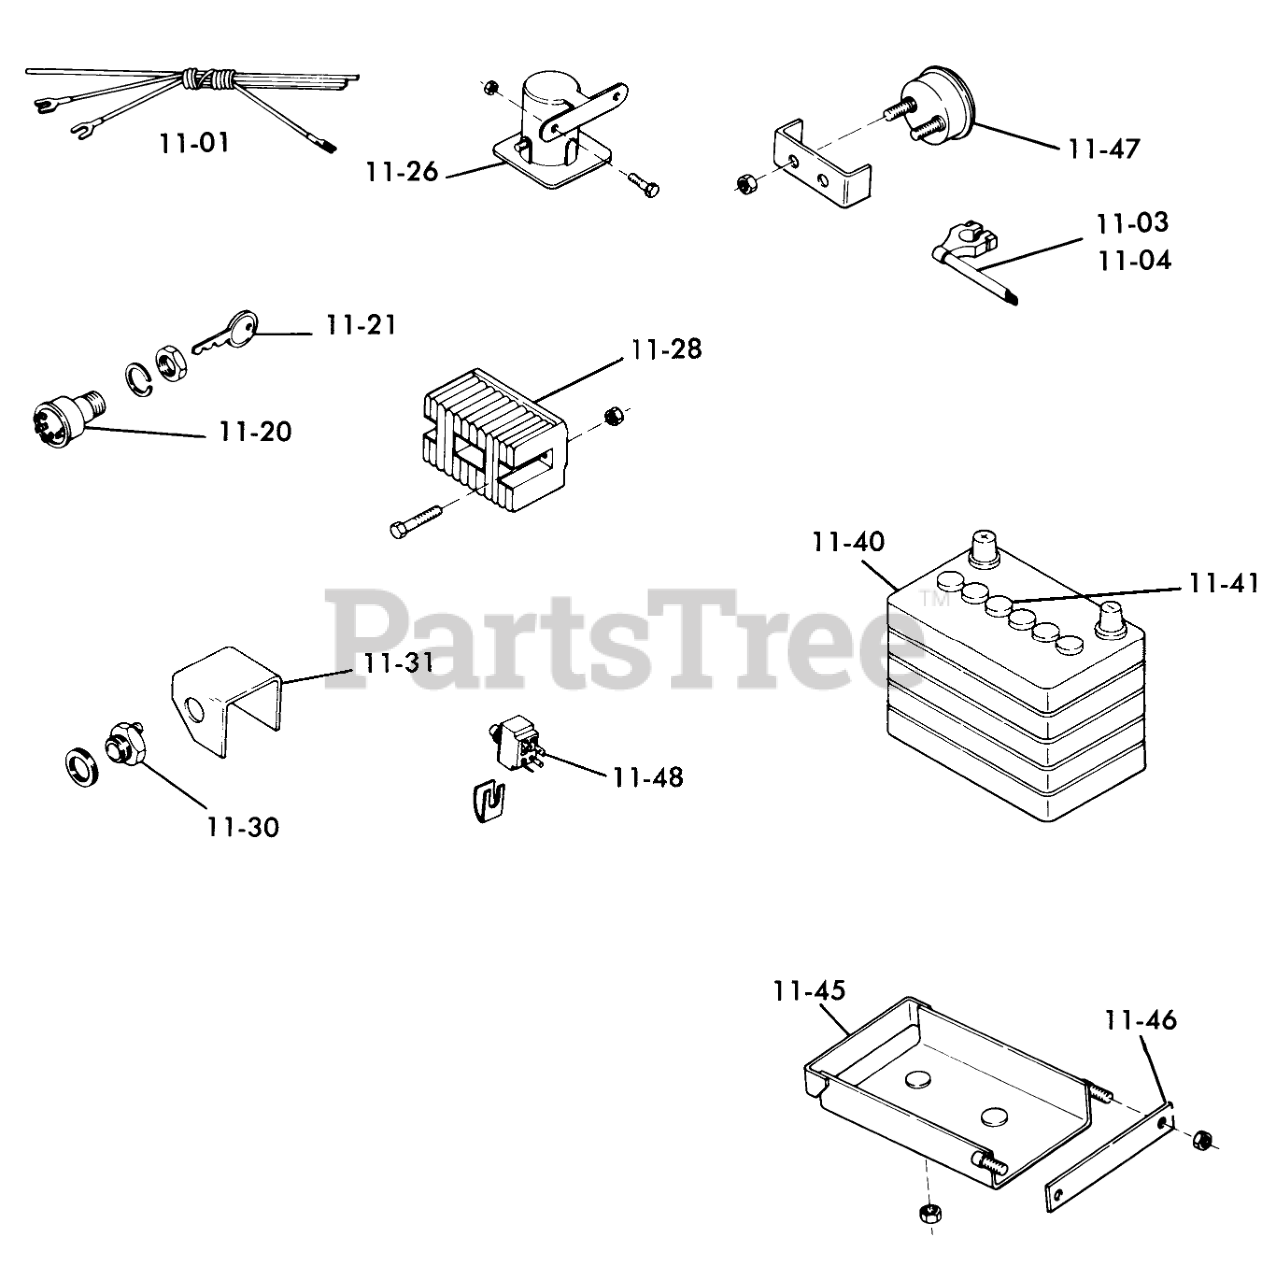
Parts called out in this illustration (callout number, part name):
11-01	WIRING HARNESS & DIA
11-01	SPEED CLIP
11-01	PLASTIC TIE
11-01	CONTROL PROTECTOR
11-02	Grommet
11-03	Wire-Ground
11-03	WIRE SOLENOID
11-03	Wire
11-03	WIRE ASSY
11-03	Wire Assy.
11-10	ASSY FUSED CONNECTOR
11-13	WIRE ASSY
11-14	Wire Harness-Lights
11-14	CLIP-WIRE
11-14	Bushing
11-20	SWITCH-IGNITION
11-20	LOCKWASHER
11-21	Key-EL
11-24	SWITCH-LIGHTS
11-25	AMMETER W/CLAMP
11-25	Clamp
11-25	HEX NUT 10-32 E.S.
11-26	Solenoid
11-26	Screw
11-28	REGULATOR-RECTIFIER
11-28	Bolt
11-28	Nut
11-30	SWITCH SAFETY
11-30	NUT-SPECIAL 9/16-18
11-31	Bracket
11-32	BOLT
11-32	Nut
11-32	WASHER
11-40	BATTERY
11-42	Cover Battery Term
11-45	BATTERY BOX ASSY R (NS)
11-45	Nut
11-46	LINK BATTERY CLAMP
11-46	Nut
11-47	Hour Meter
11-47	Clamp
11-47	SY WIRE HR METER G
11-47	Nut
11-47	NYLINER BUSHING
11-47	Wire Assy
11-47	Bushing
11-48	SWITCH-CLUTCH
11-48	CLIP-SWITCH
